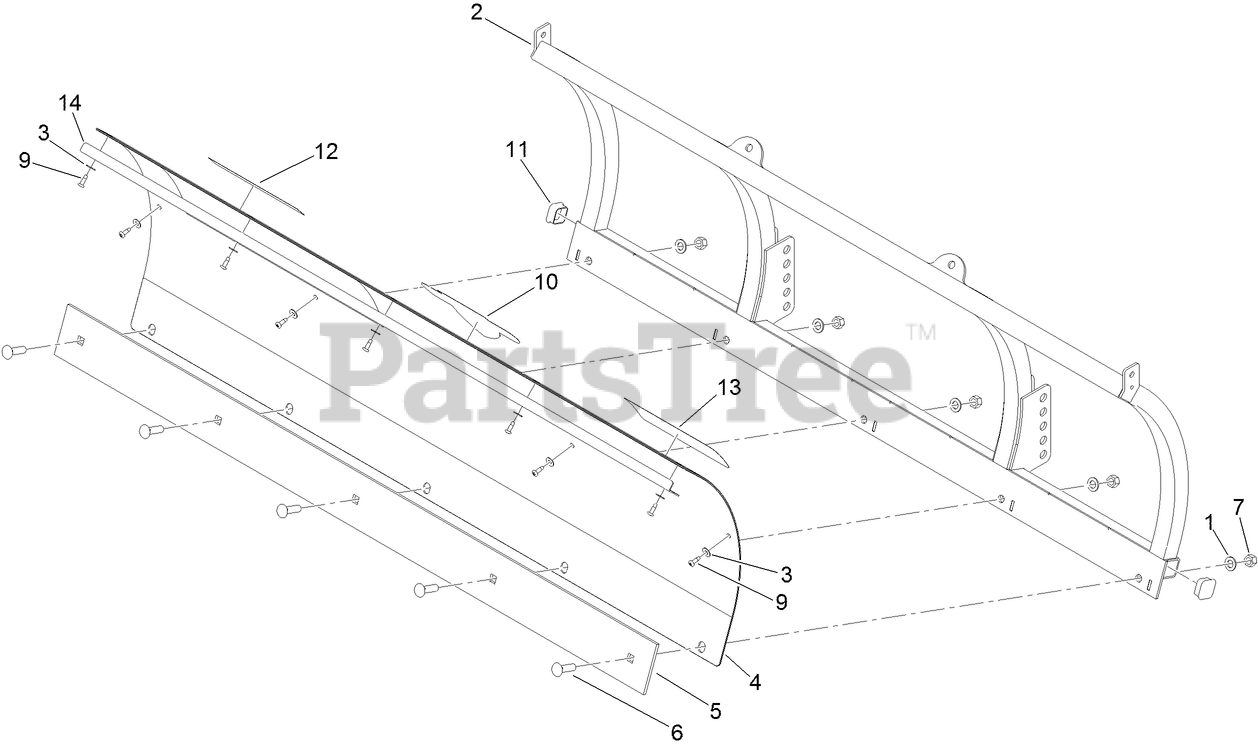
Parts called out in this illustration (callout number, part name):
1	WASHER,1/2,F436 HARD,F/W,YZN
2	BLADE ONLY, 5.0, STB, ATV
3	WASHER,1/4 FLAT,YZN
4	BLADE SKIN,POLY,5FT 0IN,ATV/UTV
5	CUTTING EDGE,5FT 0IN,ATV/UTV
6	BOLT,CARRIAGE,1/2-13X1-3/4 GR5 BLKZ
7	NUT,1/2-13,TOP L/N,GRB,CADWAX,YZN
9	SCREW,1/4-20X3/4,PH PAN HD,T/C,YZN,W/36
10	DECAL,BLADE,SMARTSHIELD
11	CAP,TUBE END,1-1/2-10-14
12	DECAL,BLADE ID,5FT,STB,ATV
13	DECAL,BLADE WARNING,PLOW,ATV/UTV
14	TOP ANGLE,BLADE,5FT 0IN STB,ATV
